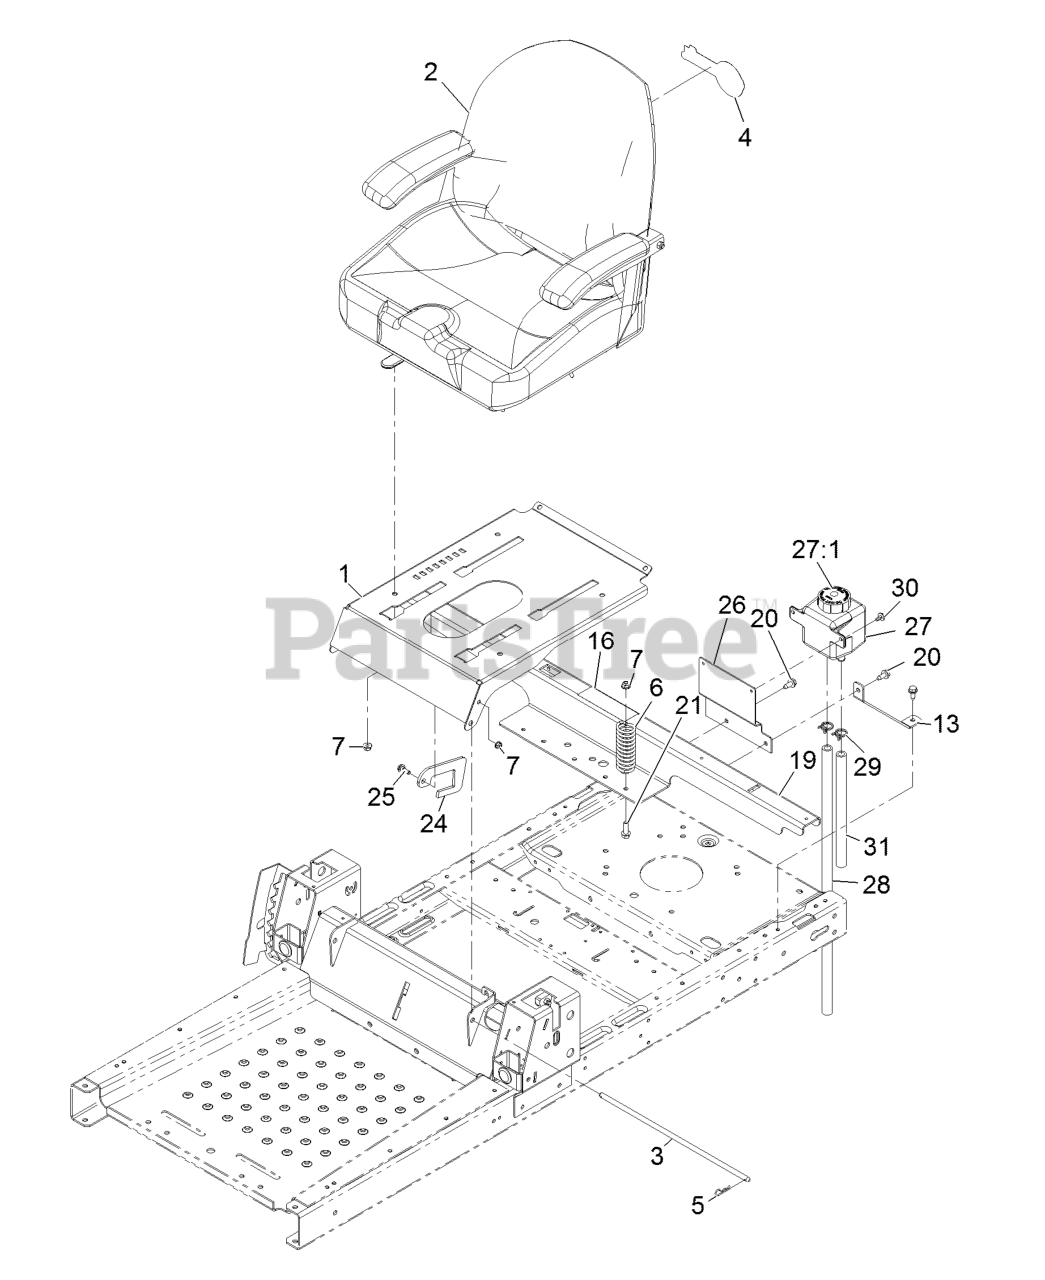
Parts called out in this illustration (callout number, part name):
2	SEAT ASM
3	ROD-STOP
5	PIN-COTTER
6	SPRING-COMPRESSION
7	NUT-HF, NI
13	SUPPORT-TANK, REAR
16	DECAL-SERVICE, CE
19	SUPPORT-POD
20	Screw-HWH 5/16-18 X 3/4 Tf
21	SCREW-HHF
24	STOP-SEAT
25	SCREW-SHOULDER
26	MOUNT-TANK
27	TANK-HYD
27:1	CAP-RESERVOIR, HYD
28	HOSE-OVERFLOW
29	CLAMP-HOSE
30	SCREW-HHFTF
31	HOSE-OVERFLOW
